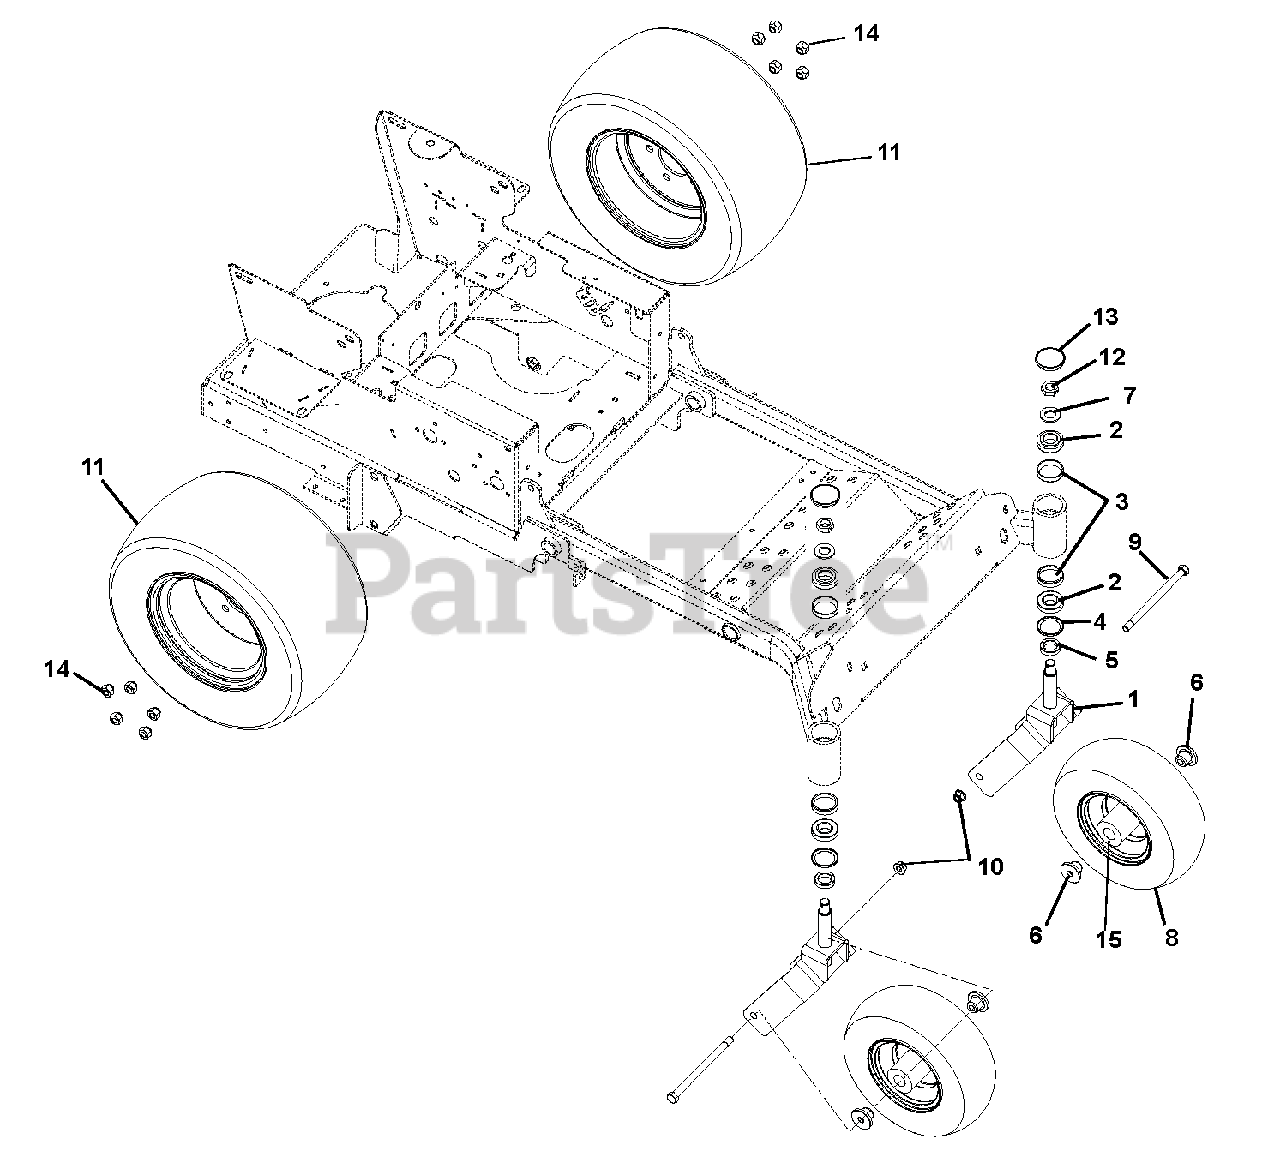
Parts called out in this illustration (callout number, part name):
1	WMT - FORK
2	BRG-CONE 1.0X.58
3	BRG-CUP1.980X.420
4	BEARING SEAL 1.5 X 2 X .18
5	SPACER 1.005X1.5075X.375
6	SPACER, FRONT WHEEL
7	@WSHR-FL-STL.812X1.50X.135YWZC
8	TIRE/WHEEL ASSY, 13X5.00-6
9	@BLT-HEX .50-13X7.50 GR5 YWZC
10	@NUT-LK-NYL-FLG .50-13 YWZC
11	TIRE/WHEEL ASSY, 20X10.00-10
12	NUT-JAM CTRLK .75-16 YWZC
13	CAP, DUST
14	WHEEL NUT .500-20 YZ
15	BRG, 25MM ID X 52MM OD X 15MM
